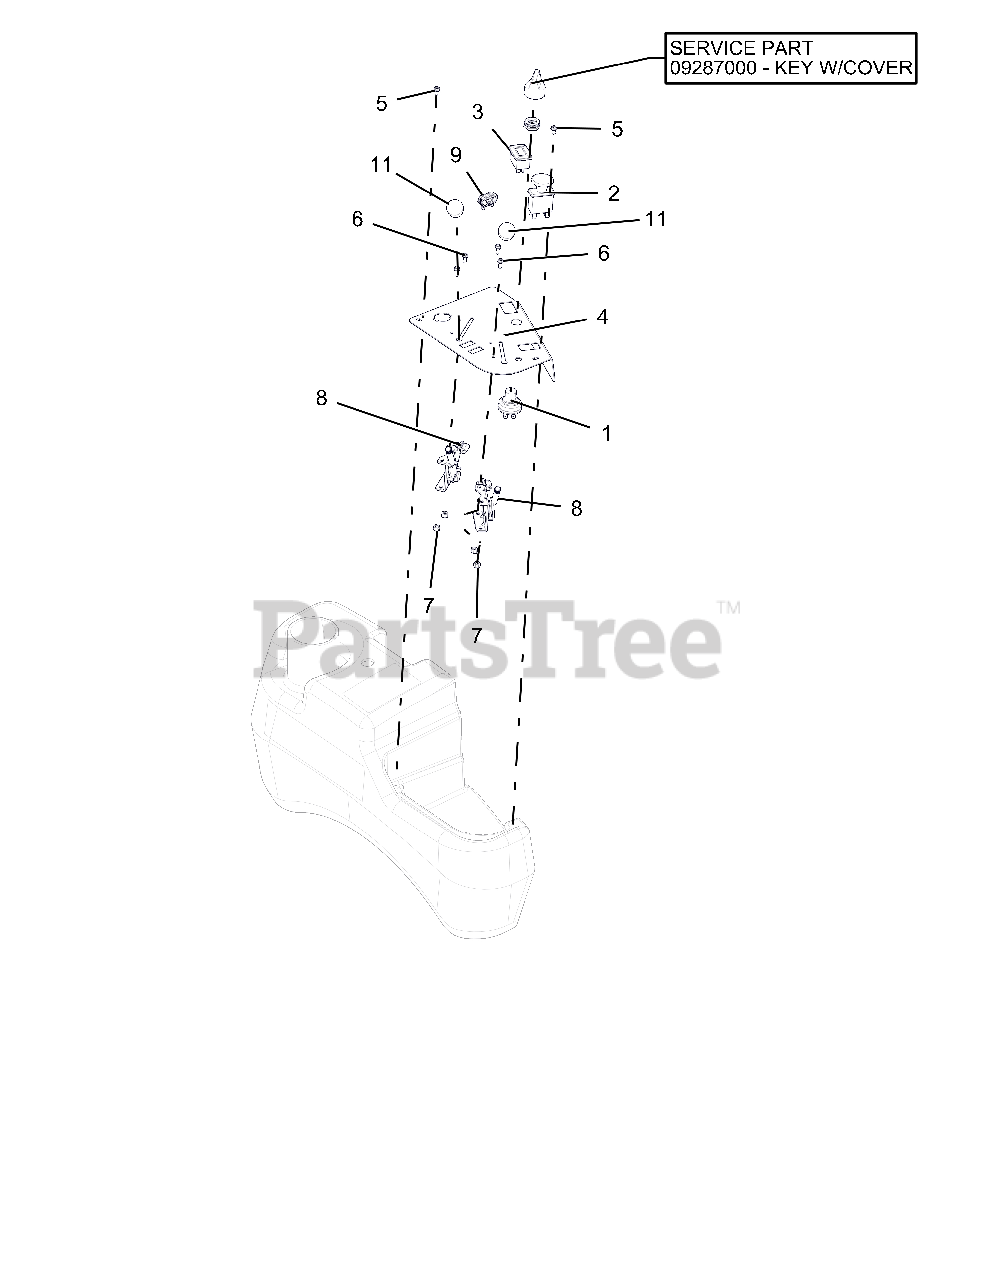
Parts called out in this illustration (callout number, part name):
1	SWITCH, IGNITION
2	SWITCH, CLUTCH
3	METER, HOUR W/MAINTENANCE
4	PANEL, CONTROL - PROTURN 100
5	SCR-MCH 10-24X.38 HWHSTAINLESS
6	@SCR-MCH 10-24X.50 HWH YWZC
7	NUT-LK-NYL #10-24 YWZC
8	CABLE, PRO-CONTROL THROTTLE
9	LIGHT, INDICATOR
11	KNOB, CONTROL BLACK .38-16X.50
12	KEY W/COVER
